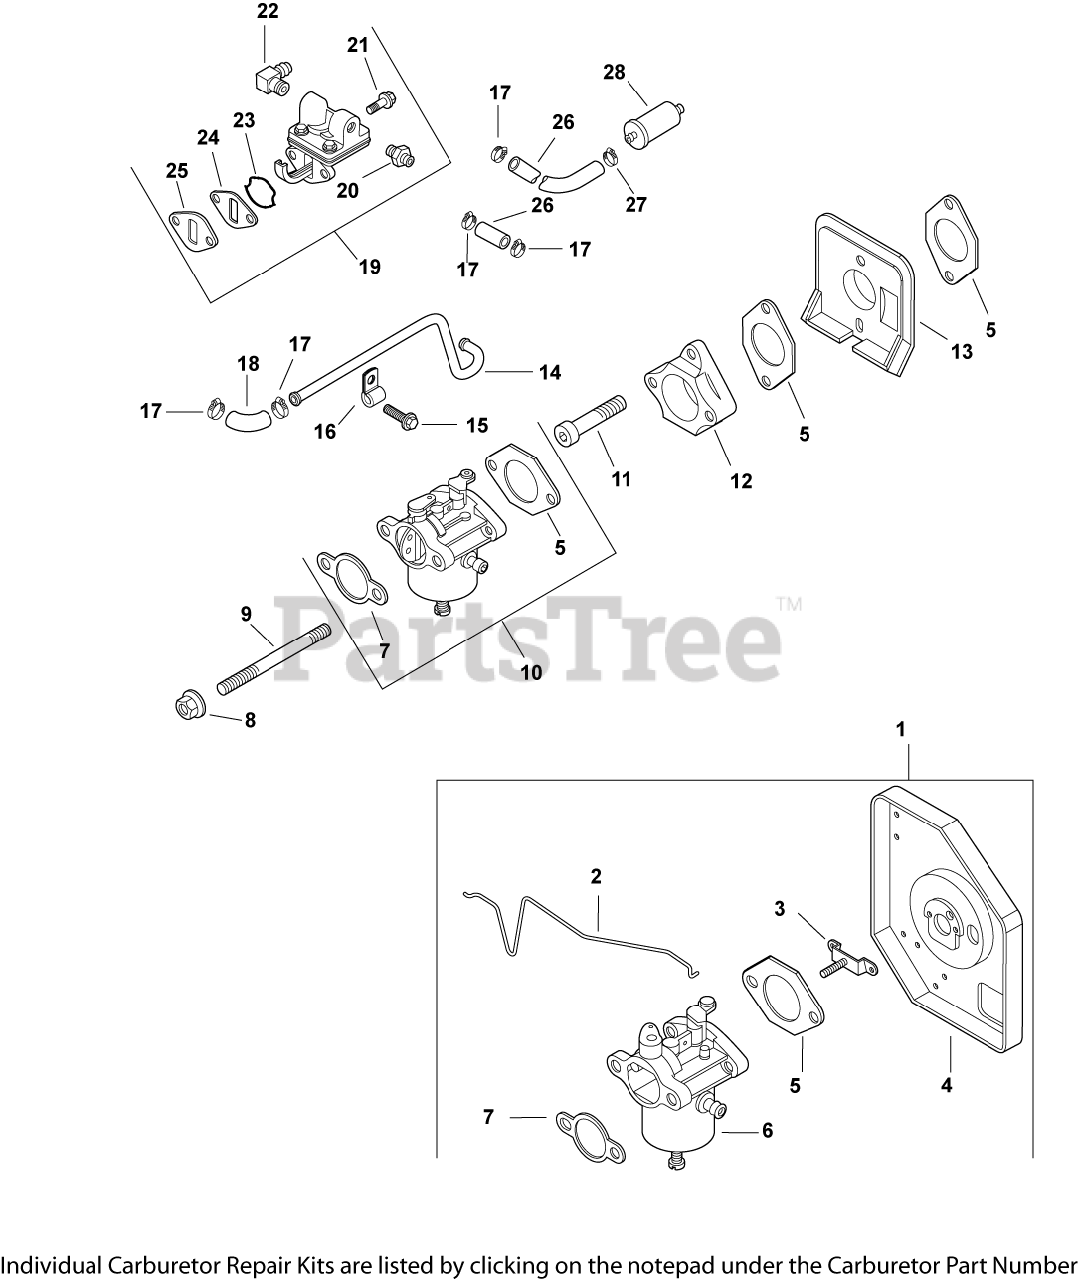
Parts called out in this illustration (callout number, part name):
1	KIT, CARB. RETROFIT
2	LINKAGE, CHOKE
3	BRACKET, AIR CLEANER
4	BASE, AIR CLEANER
5	GASKET, CARBURETOR
6	CARBURETOR W/GASEKTS - USE 12 853 139-S
7	GASKET, AIR CLEANER BASE
8	NUT, FLG M6X1.0
9	STUD,M6X1.0X116
10	KIT, CARBURETOR w/GASKETS
11	SCREW, SKT CAP M6X1.0X35
12	ADAPTER, CARBURETOR
13	DEFLECTOR, HEAT
14	LINE, FUEL - DISCONTINUED
15	SCREW, FLG THD FRM M5X.8X10
16	CLIP, TUBE & WIRING (KM)
17	CLAMP, HOSE (KM)-USE 25 237 31-S
18	HOSE, FUEL LOW-PERMEATION
19	KIT, FUEL PUMP
20	CONNECTOR
21	SCREW,FLG THD FRM M6X1.0X20-(#25086396S)
22	CONNECTOR, 90 DEG. HOSE
23	O-RING, FUEL PUMP
24	SPACER, FUEL PUMP
25	GASKET, FUEL PUMP
26	HOSE,LW PERM.FUEL 24.00"-USE 25 111 81-S
27	CLAMP, BAND SPRING HOSE-(#2523737S)
28	FILTR,FUEL 75 MICRON (GRAVTY FEED)
